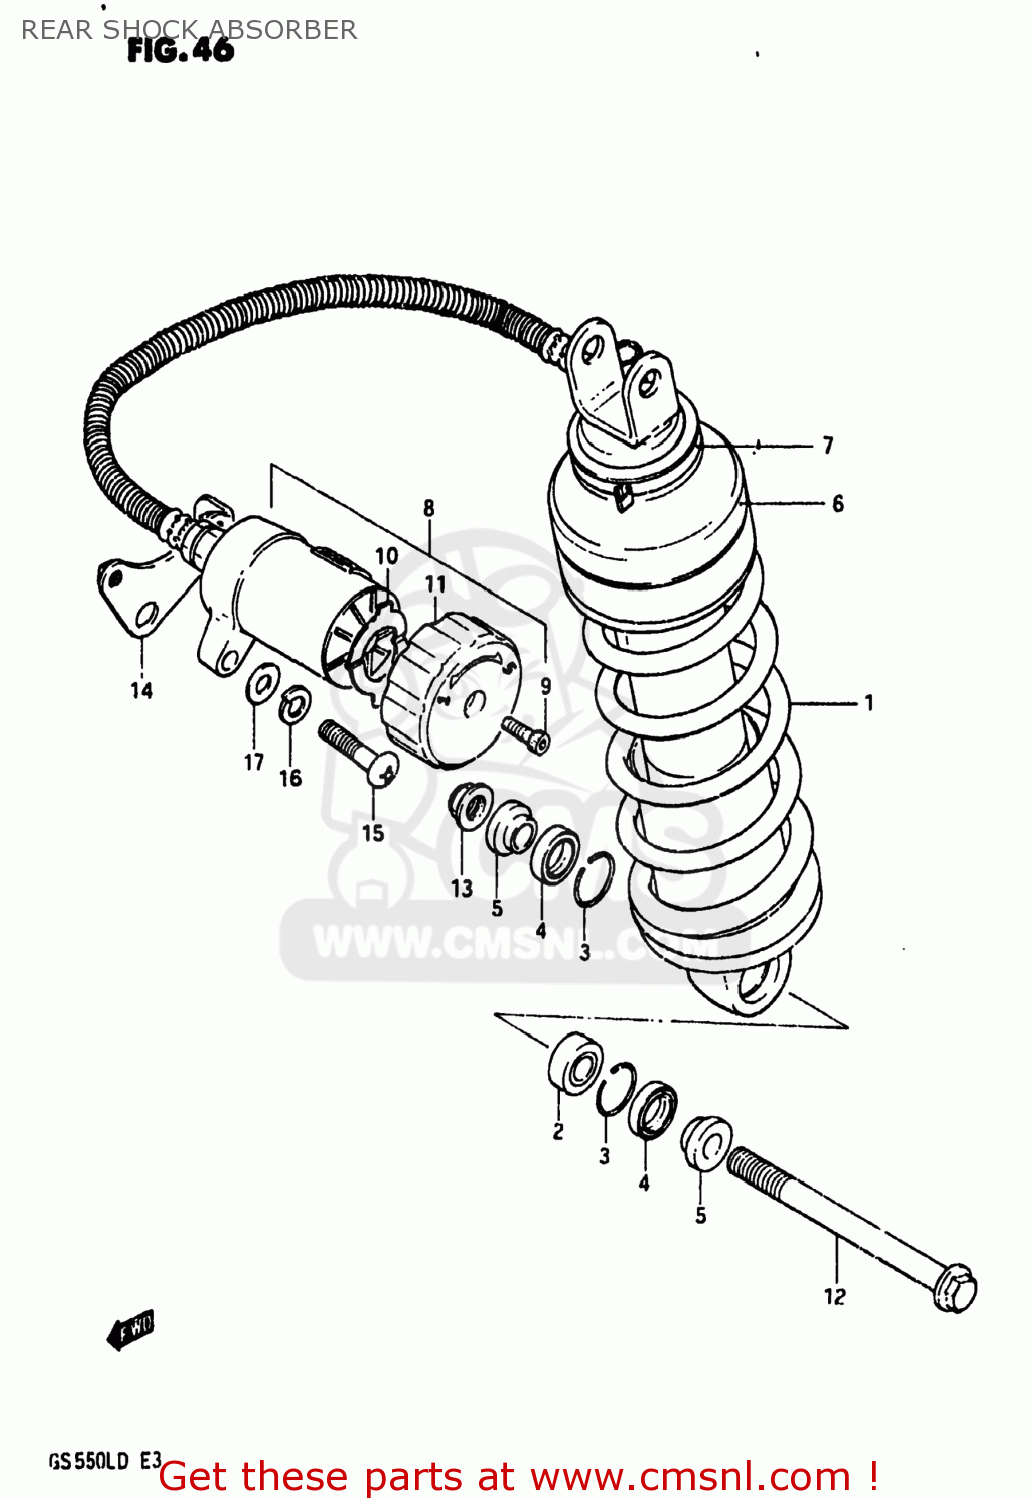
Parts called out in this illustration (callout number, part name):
1	ABSORBER ASSEMBLY,REAR SHOCK
2	BEARING
3	RING
4	DUST SEAL
5	COLLAR
6	COVER
7	BAND
9	BOLT
10	PLATE SET
11	LEVELING PLATE
12	BOLT(10X115)
13	NUT
14	BRACKET,RESERVOIR TANK
15	SCREW 6X30
16	LOCK WASHER
17	WASHER
